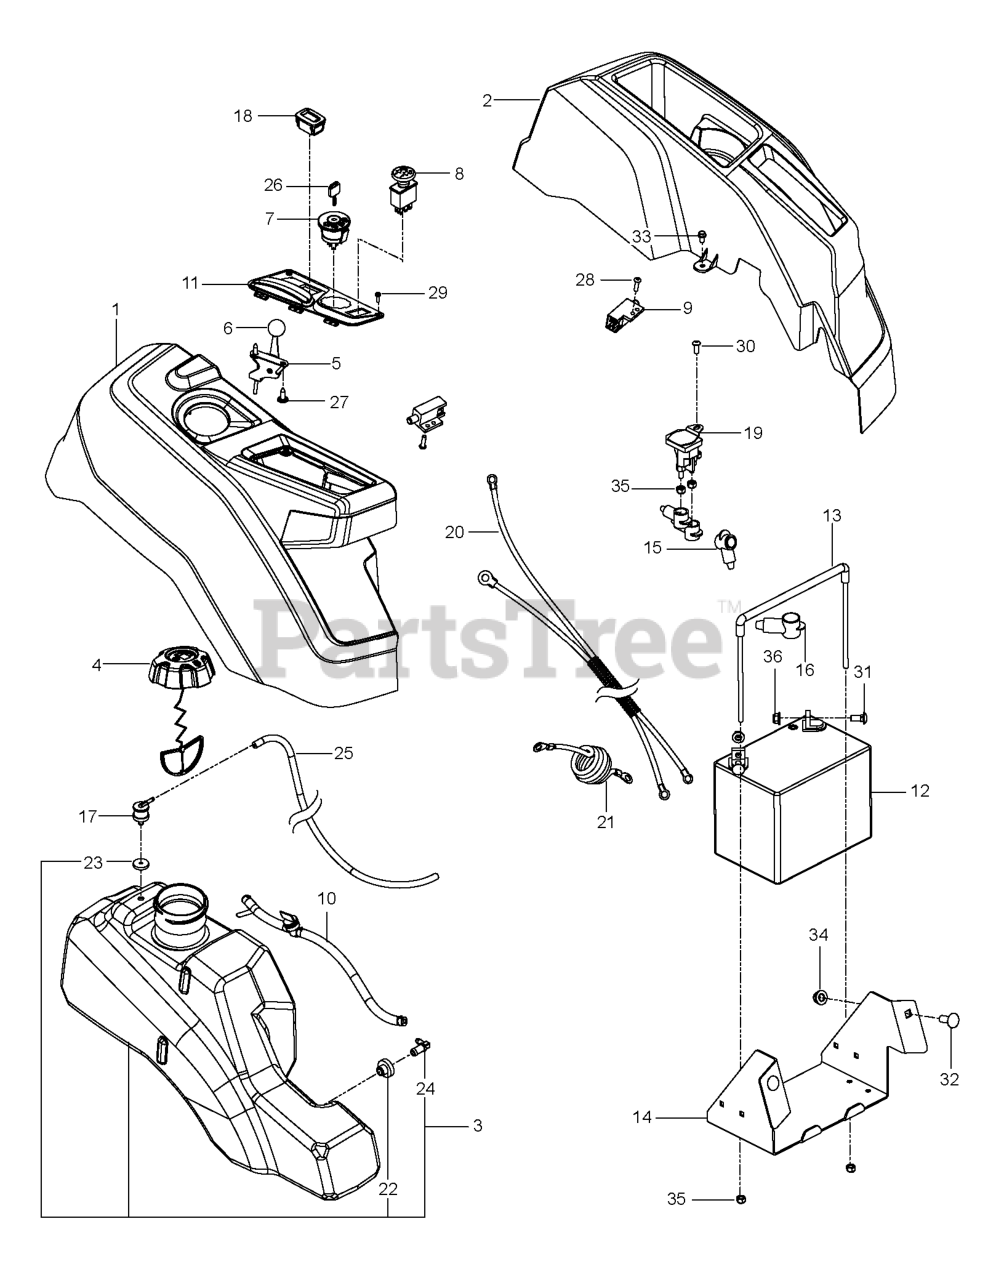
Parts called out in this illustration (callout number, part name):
1	CONSOLE.ASSY.RZ.REFRESH.RH
2	CONSOLE.LH.ASM
3	ASM.FUEL.TANK.LG.3".W/O SHIELD
4	FUEL CAP
4	CAP ASSY FUEL 3" GRAY
5	THROTTLE CABLE
6	KNOB.ROUND.BALL.BLACK
7	RP IGNITION SWITCH
8	RP SWITCH.PTO.8.TERMINAL.RED
9	SWITCH.INTLK.RZ.RFRSH.BUTTON
10	FUEL.HOSE.SHUT.OFF.ASM.10".3"
11	CONTROL.PANEL.RZ.REFRESH.RH
12	BATTERY, 12 V 330 AMP
13	BATTERY TIE DOWN ASSEMBLY
14	BOX BATTERY RZ BLACK
15	TERMINAL COVER
17	VALVE.FUEL.CHECK
18	GUAGE.SRVCMNDR.HRMTR.
19	SOLENOID.W/BRASS.PLUNGER
20	HARNESS.BTTRY.CABLE.RZ.REFRESH
21	CABLE POSITIVE, LONG
22	BUSHING OUTLET T
23	GROMMET.ROV.SENTEC
24	STEM FUEL TANK
25	HOSE.3/16".VAPOR.LINE.23"LGTH
26	KEY MLD GEN DELTA
27	SCREW.PAN.HEAD.#10
28	SCR #10-24 X .75 SKT HD BLK
29	SCREW 6-19X.437
30	SCR 1/4-20 X 5/8 BTN SKT HD ZD
31	RP BOLT 5/16-18 X3/4 ZN/YEL GR
32	BOLT D
33	SCREW
34	NUT 3/8-16 HEX FLG NYLOC ZD
35	LOCKNUT.NYLOC.1/4-20
36	5/16-18 NYLOC FLANGE NUT
